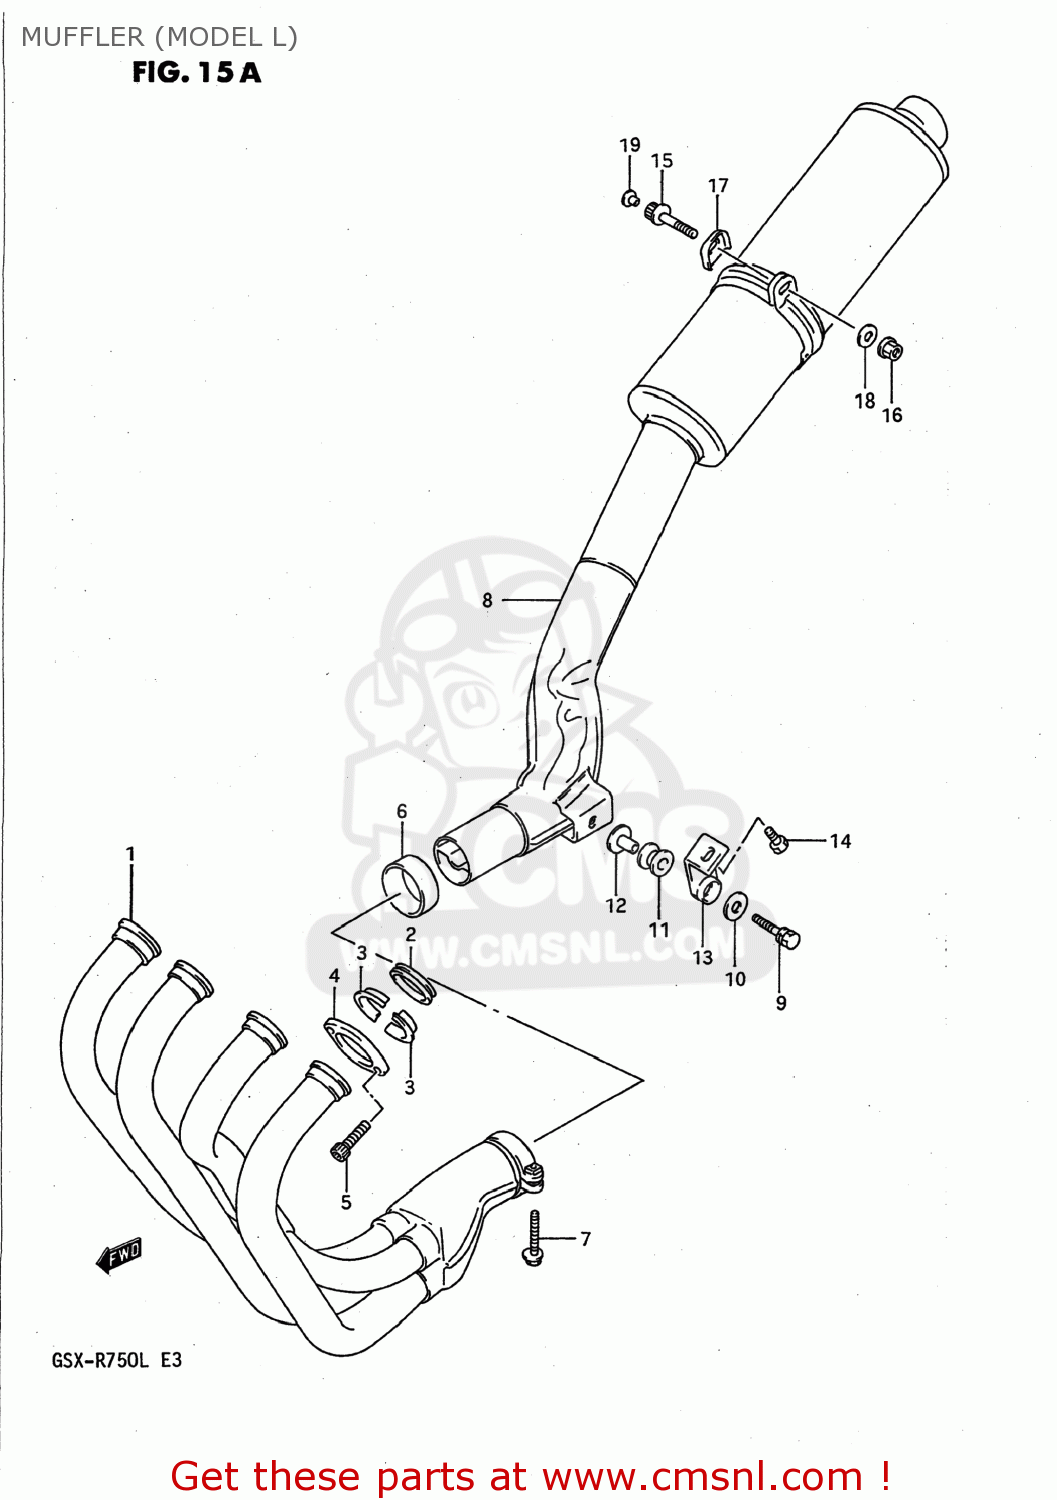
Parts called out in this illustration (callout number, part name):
1	EXHAUST ASSY
2	GASKET,EXHAUST (NAS)
3	PLATE,EXHAUST PIPE
4	CLAMP,EXHAUST PIPE
5	BOLT
6	CONNECTOR,MUFFLER
7	BOLT 8X45
8	MUFFLER ASSEMBLY
9	BOLT 8X35
10	WASHER
11	CUSHION
12	SPACER(8.6X12X18.5)
13	DAMPER COMP,MUFFLER SUPPORT F
14	BOLT(8X20)
15	BOLT
16	NUT
17	WASHER,MUFFLER SUPPORT
18	WASHER (10.5X24X2.3)
19	CAP(OD:12)
